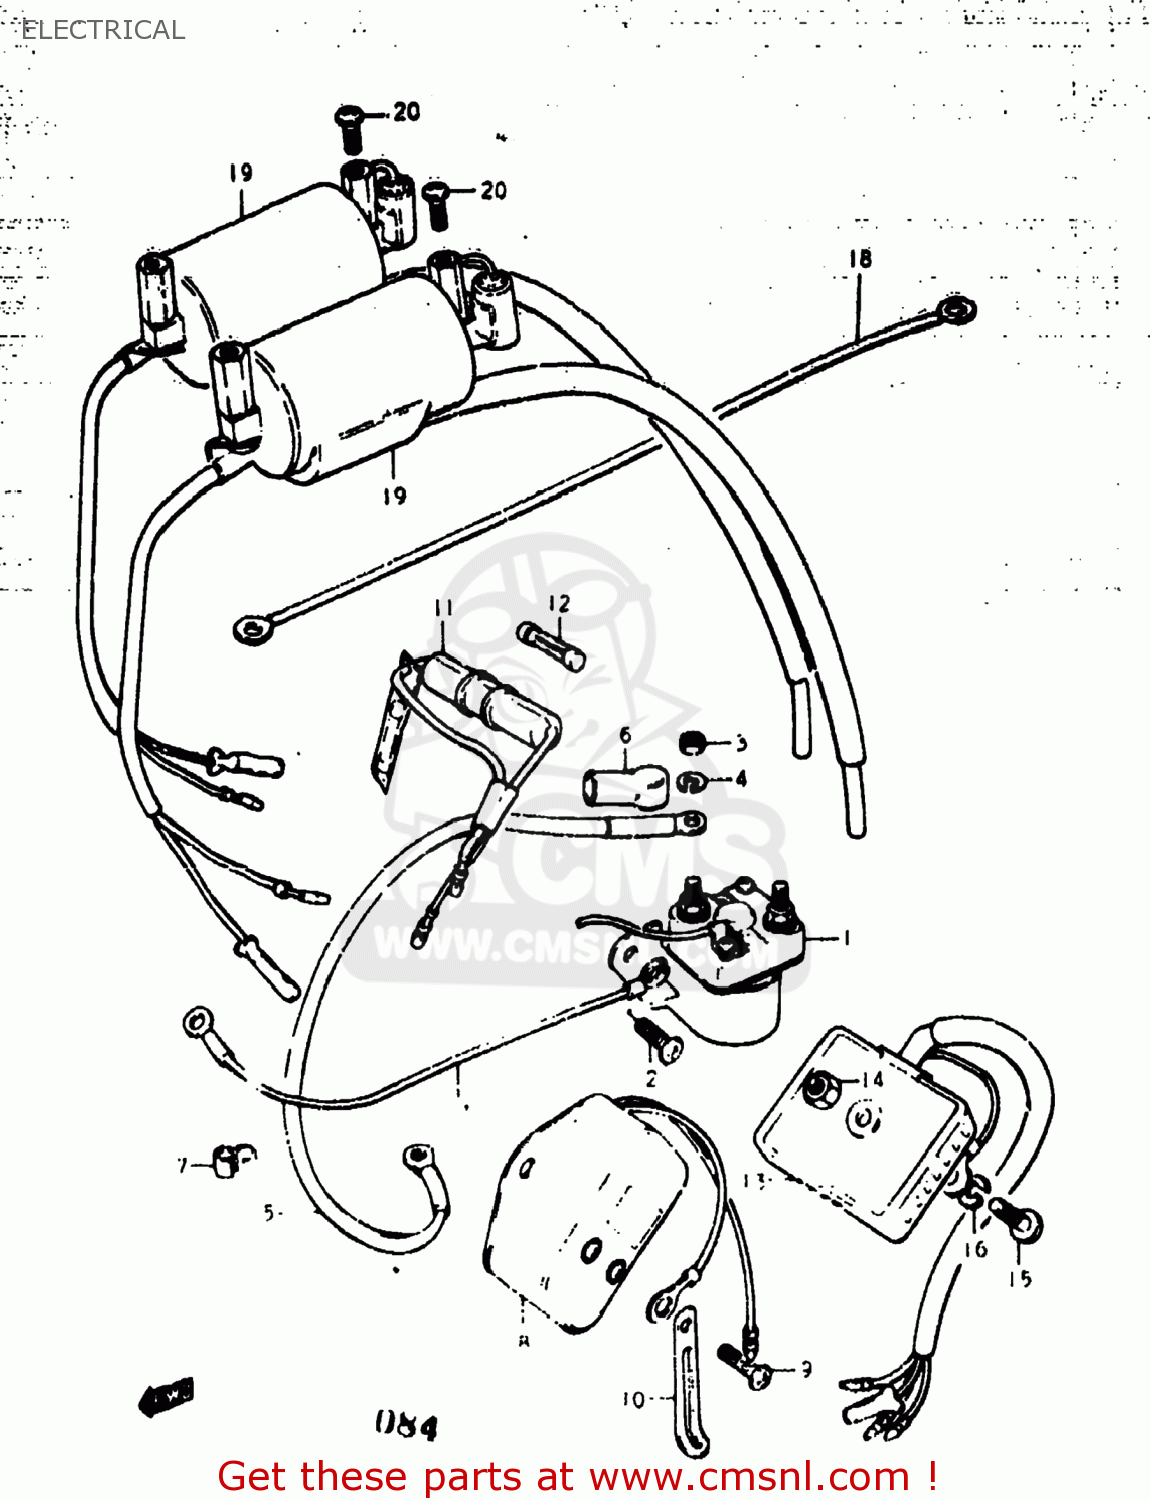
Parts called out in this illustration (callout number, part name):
1	RELAY ASSY,STARTING MOTOR
2	SCREW
3	NUT
4	LOCK WASHER
5	WIRE,STARTER MOTOR LEAD
6	CAP,STARTER RELAY
7	CLIP
8	REGULATOR ASSEMBLY
9	SCREW
10	CLAMP L:35
11	BOX ASSEMBLY,FUSE
12	FUSE(15A)
13	RECTIFIER ASSY
14	NUT
15	LOCK WASHER
16	SCREW
17	WIRE
18	WIRE
19	COIL ASSEMBLY,IGNITION
20	SCREW
